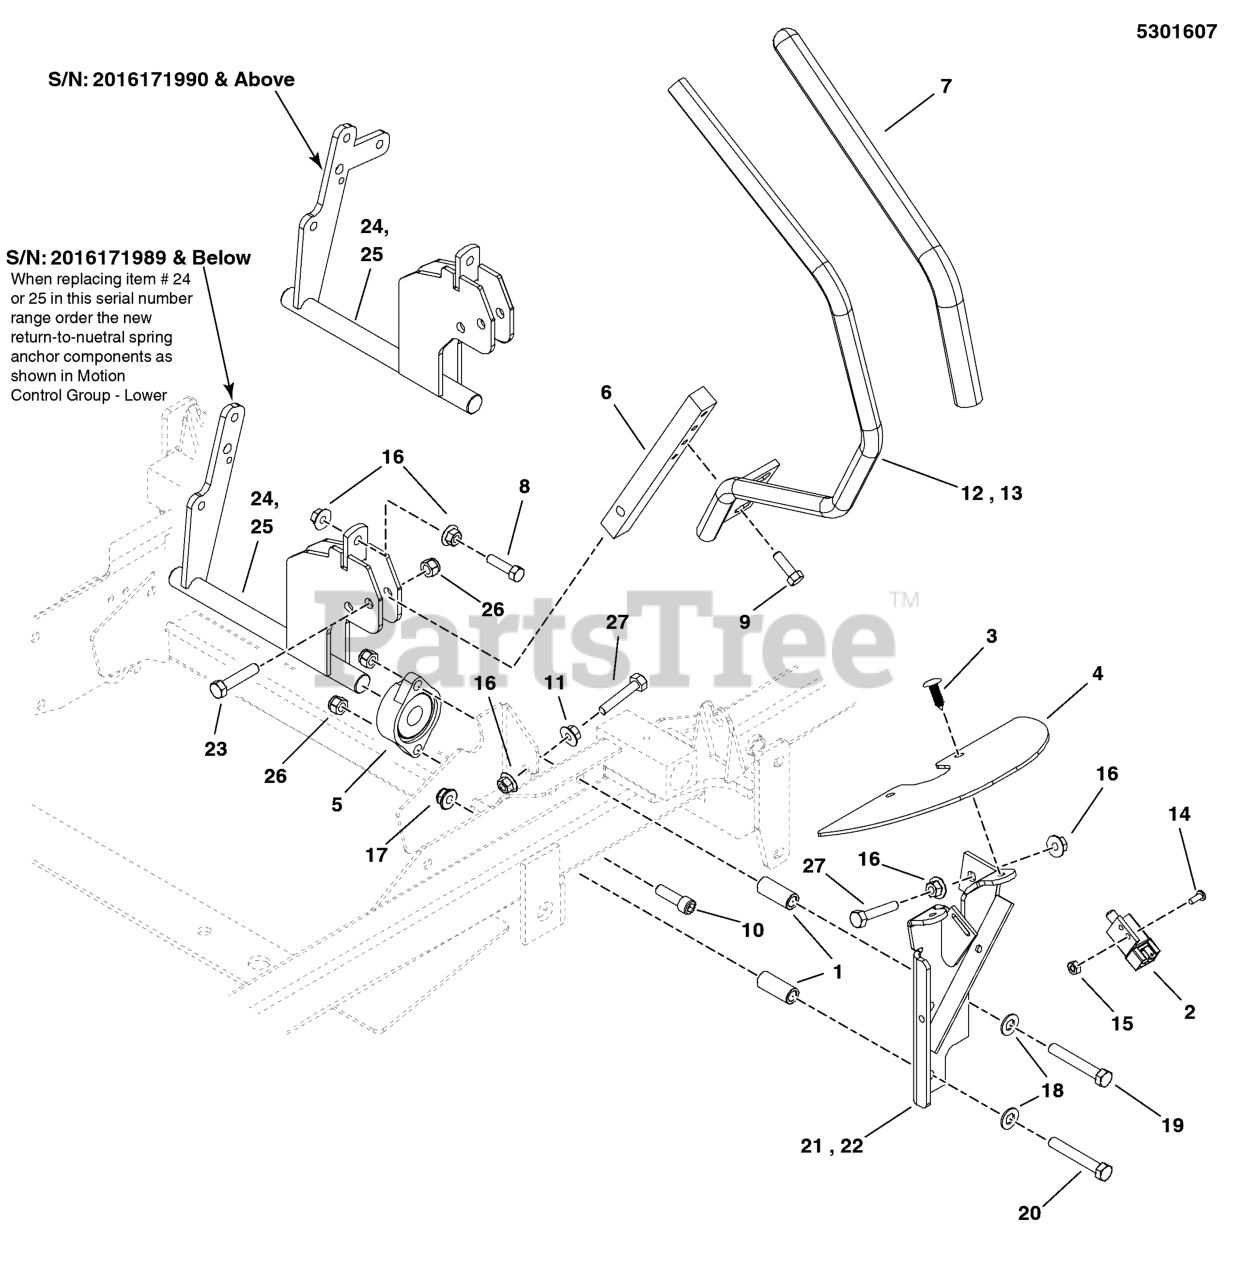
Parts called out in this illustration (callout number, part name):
1	SPACER, .39 X .63 X 1.50
2	SWITCH, PLUNGER, N.O.
3	PUSH RIVET (TREE TYPE), BLACK
4	GUARD, RUBBER MOTION CONTROL
5	BEARING, FLANGE
6	MOUNT, CONTROL ARM - BLK
7	GRIP, FOAM, 3/4 ID, 16 LONG
8	BOLT, 5/16-18 X 1-1/4 GD5 YZ
9	SCREW, 5/16-18x0.750, GR5, WHIZ-LOCK, ZC
10	BOLT, 3/8-16 X 1-1/4 SHCS
11	NUT, 5/16-18 HEX SERRATED FLANGE (SMALL)
12	WELD, HANDLE, MOTION CONTROL, LH - BLK
13	WELD, HANDLE, MOTION CONTROL, RH - BLK
14	SCREW- #10-24 X 1/2 ROUND PHILLIPS
15	NUT, #10-24 HEX
16	NUT, 5/16-18 HEX SERRATED FLANGE (LARGE)
17	NUT, 3/8-16 HEX NYLOCK FLANGE
18	WASHER, 3/8 SAE
19	BOLT, 3/8-16 X 3" GD5 CZ
20	BOLT, 3/8-16 X 2-1/2" GD5 CZ
21	WELD, NEUTRAL LOCK - LH - BLK
22	WELD, NEUTRAL LOCK - RH - BLK
23	BOLT, 3/8-16 X 1-3/4" GD5 CZ
24	WELD, CONTROL SHAFT - RH - BLK
25	WELD, CONTROL SHAFT - LH - BLK
26	NUT, 3/8-16 HEX NYLON LOCK
27	BOLT- 5/16-18 X 1-1/2 GD5 TFL
